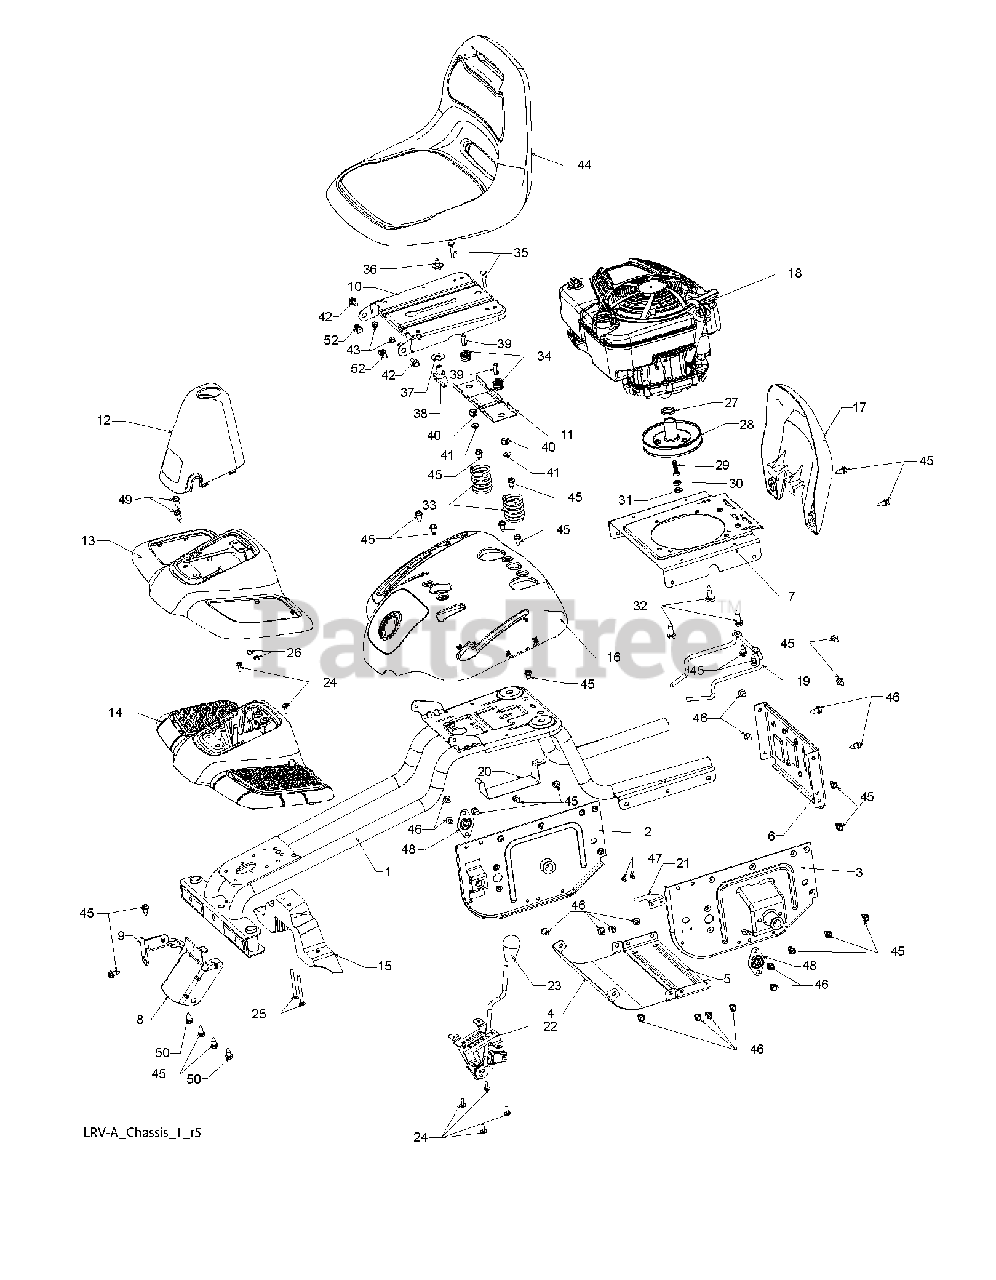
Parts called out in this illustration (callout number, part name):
1	CHASSIS.WLD.26".LRV
2	SUPPORT, AXEL LH
3	RP SUPPORT, AXLE RH
4	SHIELD, TRANSAXLE FRONT
5	STRAP.CROSS.FRICTION.DRIVE
6	COVER, FRICTION DRIVE
7	PLATE, ENGINE
8	BRACKET, CHASSIS FRONT
9	BRACKET, STEERING SUPPORT
10	PAN.ASM.SEAT.1SLOT
11	BRKT.MNTNG.SWITCH.SEAT.BLACK
12	BOOT, DUST LRV (2 2)
13	FOOTREST.AESTHETIC.WE.GRN.LRV
14	STRUCTURE, FOOT REST
15	SUPPORT, FOOT REST
16	FENDER.CNTRL.PNL.WE.GRN.LRV
17	GUARD.ENGINE.LRV
19	KEEPER, BELT
20	BRACKET, BATTERY LRV
21	LEVER, SWITCH
22	CABLE.ASM.CLUTCH.W/BRACKET
23	KNOB.OVAL.CUSTOM.BLACK
24	SCREW.#10 X 0.750.BOS (2 2)
25	BOLT.CARRIAGE
26	NUT
27	SPACER.ENGINE.B&S.LRVA
28	DISC, FRICTION ASM
29	BOLT, SCKT HD 3/8-24 X 1 .25
30	BEARING.BALL.689ZZ
31	SPACER.NEUTRAL
32	BOLT 3/8-16X1-1/8
33	SPRING COMPRESSION
35	BOLT.ROUND.HEAD.SQUARE.NECK
36	BOLT,SHOULD
38	KNOB.SEAT.ADJ.WINGNUT
39	SPACER SPLIT 28X.96
41	NUT T
42	BOLT.SHOULDER.5/16-18
43	NUT.71038.31-18.HEX.NYLOCK
44	SEAT.SUBASY.OPP.WEEDEATER.LRVA
45	SCREW
46	SCREW LT
48	BEARING FLANGE BALL
49	SCREW 5/16-18X1
50	BOLT.SHOULDER.5/16-18X
52	PUSH CLIP
